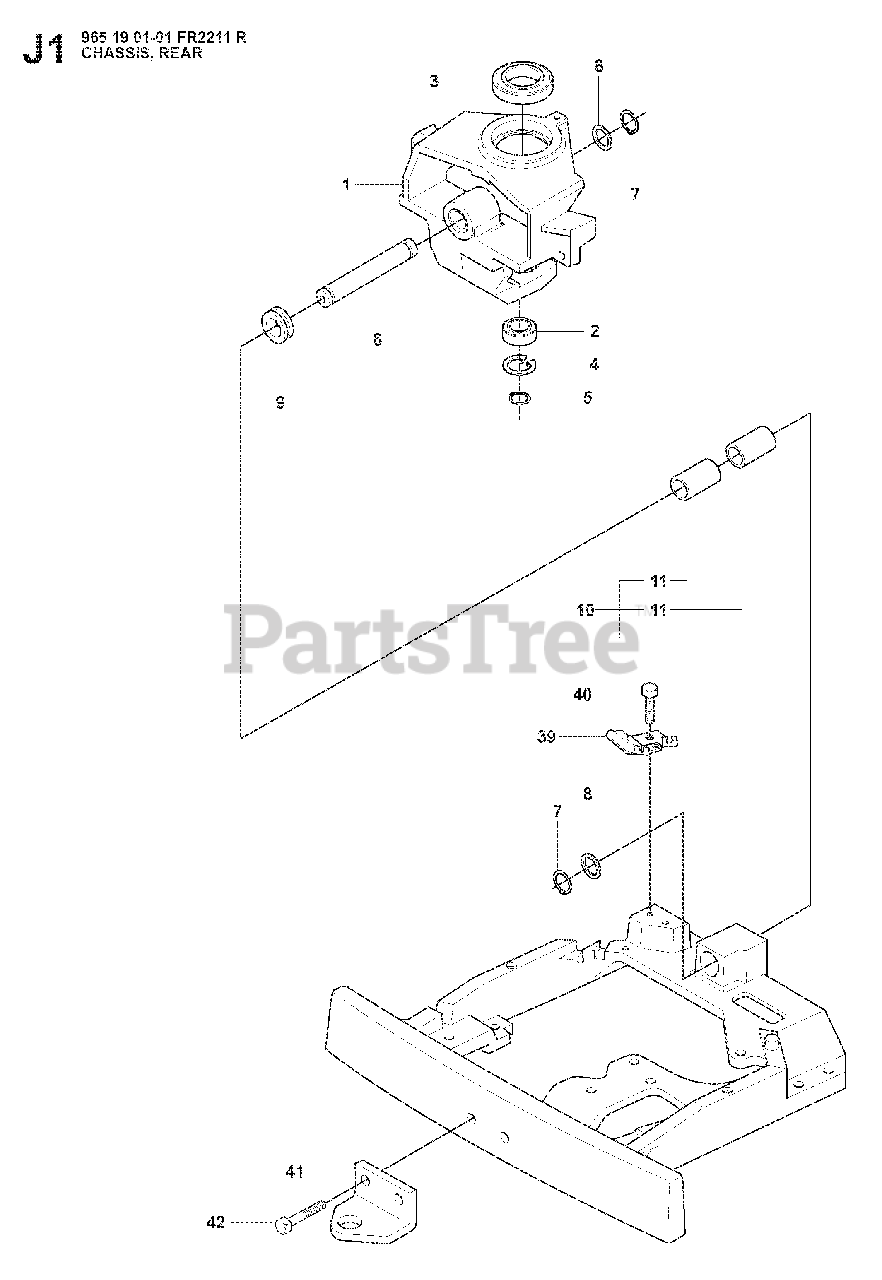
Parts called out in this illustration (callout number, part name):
2	BALL BEARING 6005-2RS
3	BALL BEARING 6010 2RS1
4	CIRCLIP SGH 47
5	RETAINING RING SGA 25
7	RETAINING RING SGA 25
41	DRAW RING
42	SCREW M10X25
